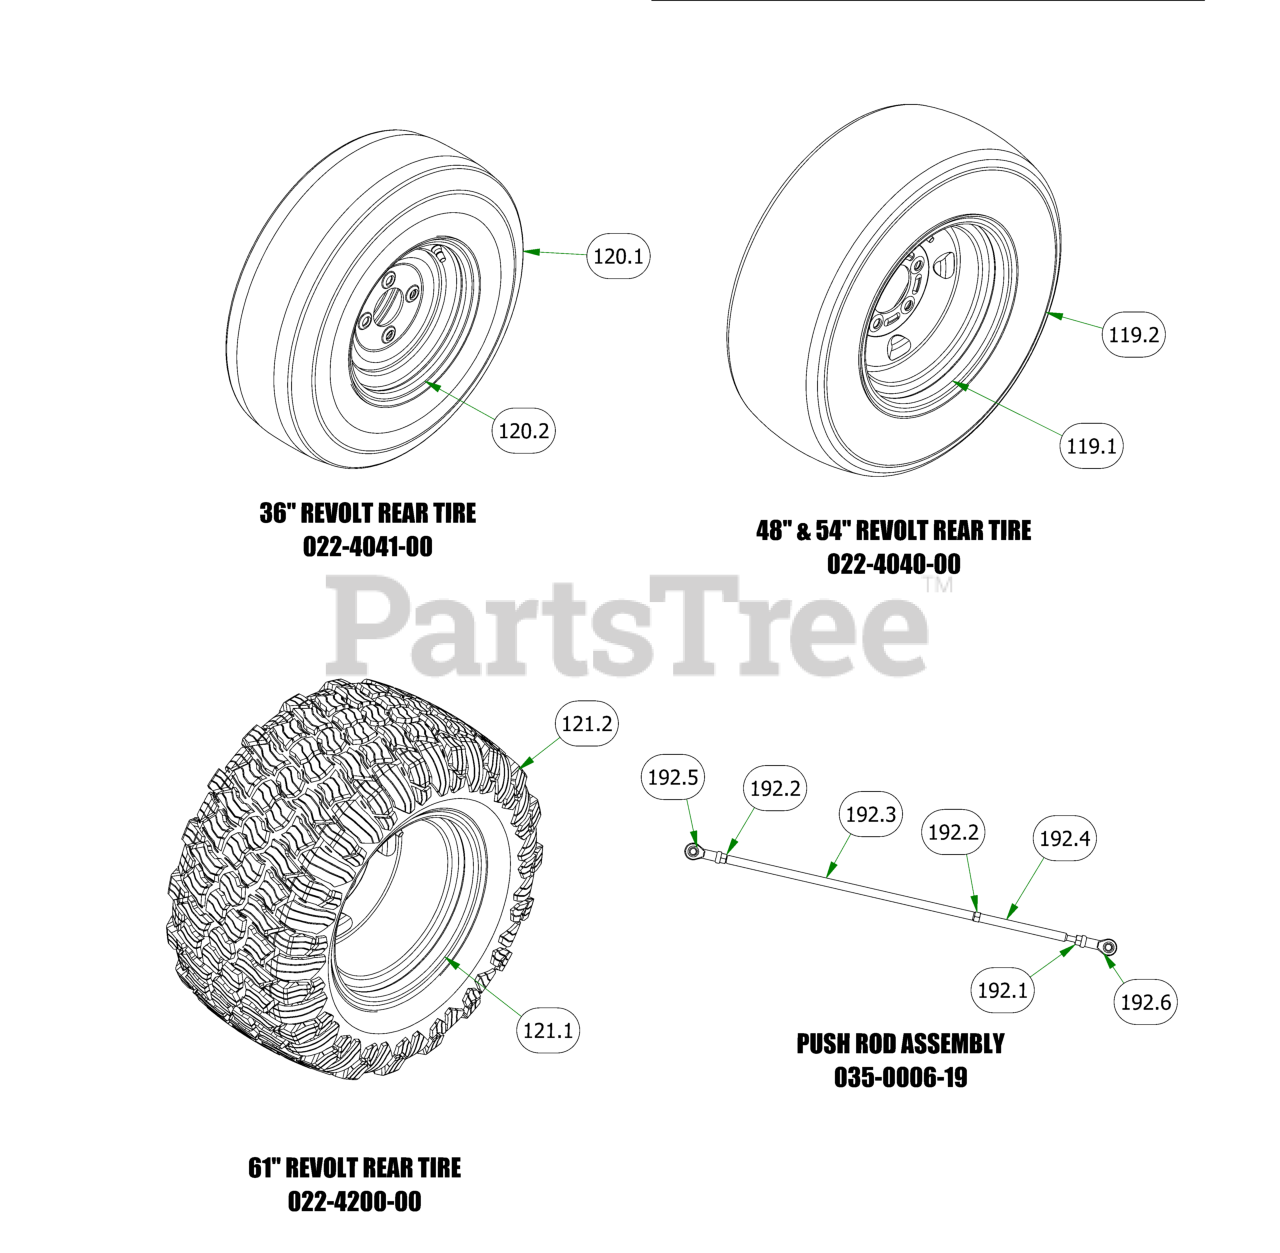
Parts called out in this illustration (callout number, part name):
119	23x9-12 Reaper Turf Tire & Wheel Assembly
119.1	12x7" Black Wheel
119.2	23x9-12 Reaper Turf Tire Only
120	21/7x10 Reaper Tire-36 Revolt
120.1	36" Revolt Reaper Tire
120.2	36" Revolt Wheel
121	23x11-12 Reaper Turf Assembly
121.1	12x8.5 Black Wheel
121.2	Tire, 23/11x12 Reaper Turf
192	2019 Revolt Push Rod Assembly
192.1	5/16" LH Fine Threaded Jam Nut
192.2	3/8" Fine Threaded Jam Nut
192.3	2019 Revolt Push Rod
192.4	2019 Renegade Push Rod Adjuster
192.5	Spherical Rod End - Outlaw
192.6	Spherical Rod End - Outlaw
